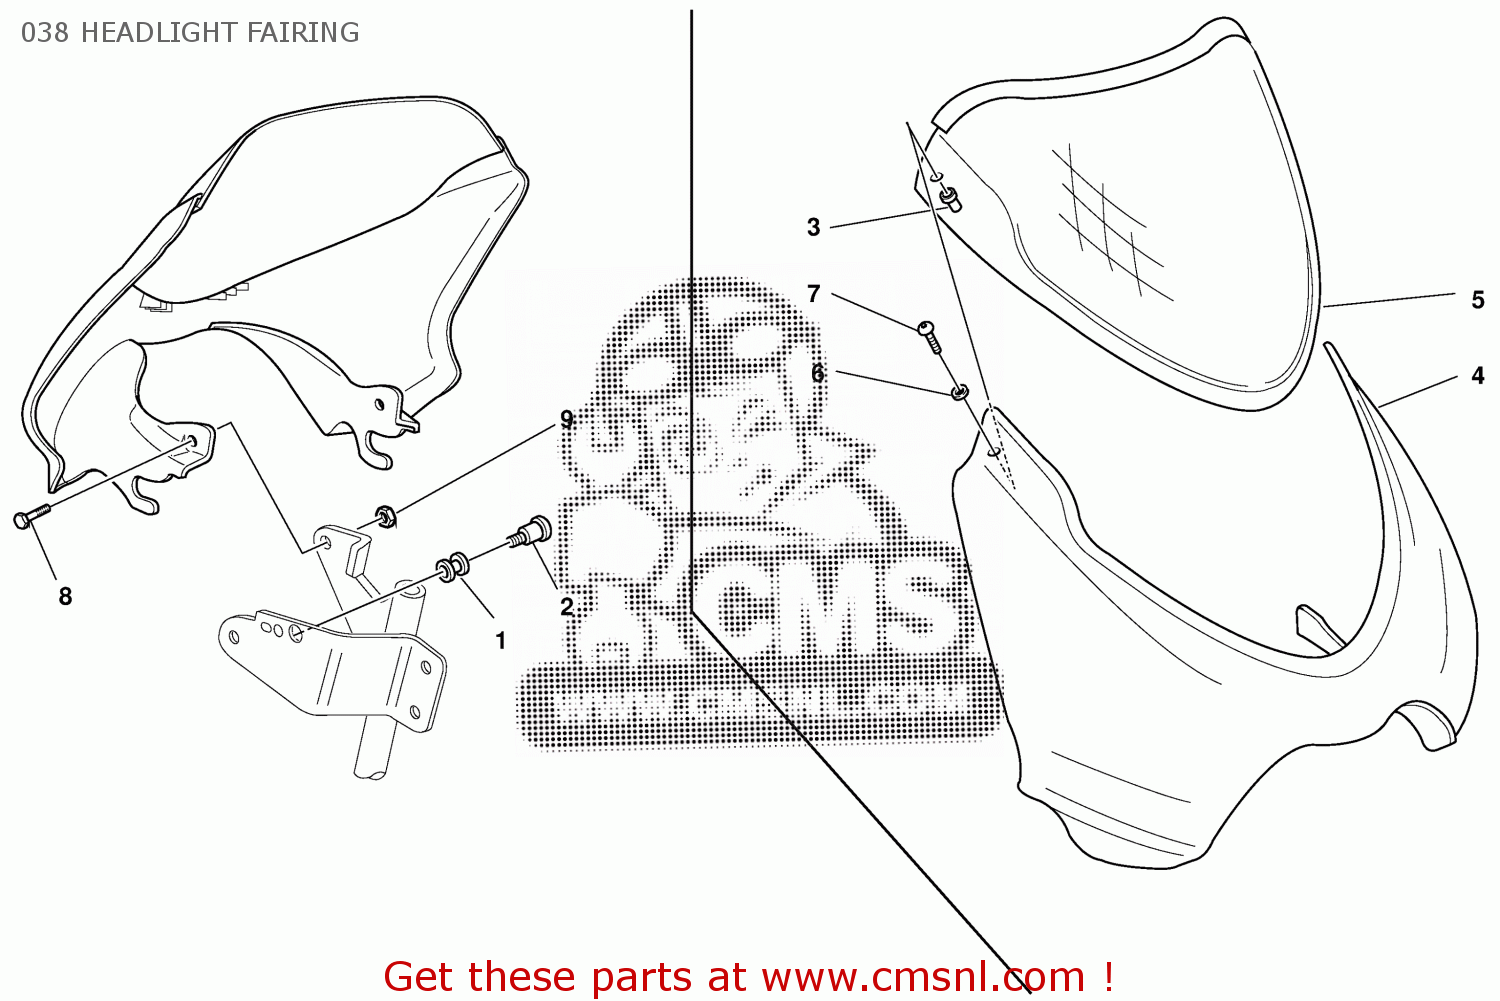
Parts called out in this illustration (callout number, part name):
1	DAMPER
2	SCREW
3	THREADED INSERT
4	COWLING
5	WINDSHIELD
6	WASHER, NYLON 11X5.2X0.5
7	SCREW
8	BOLT 6X16
9	NUT 6MM
